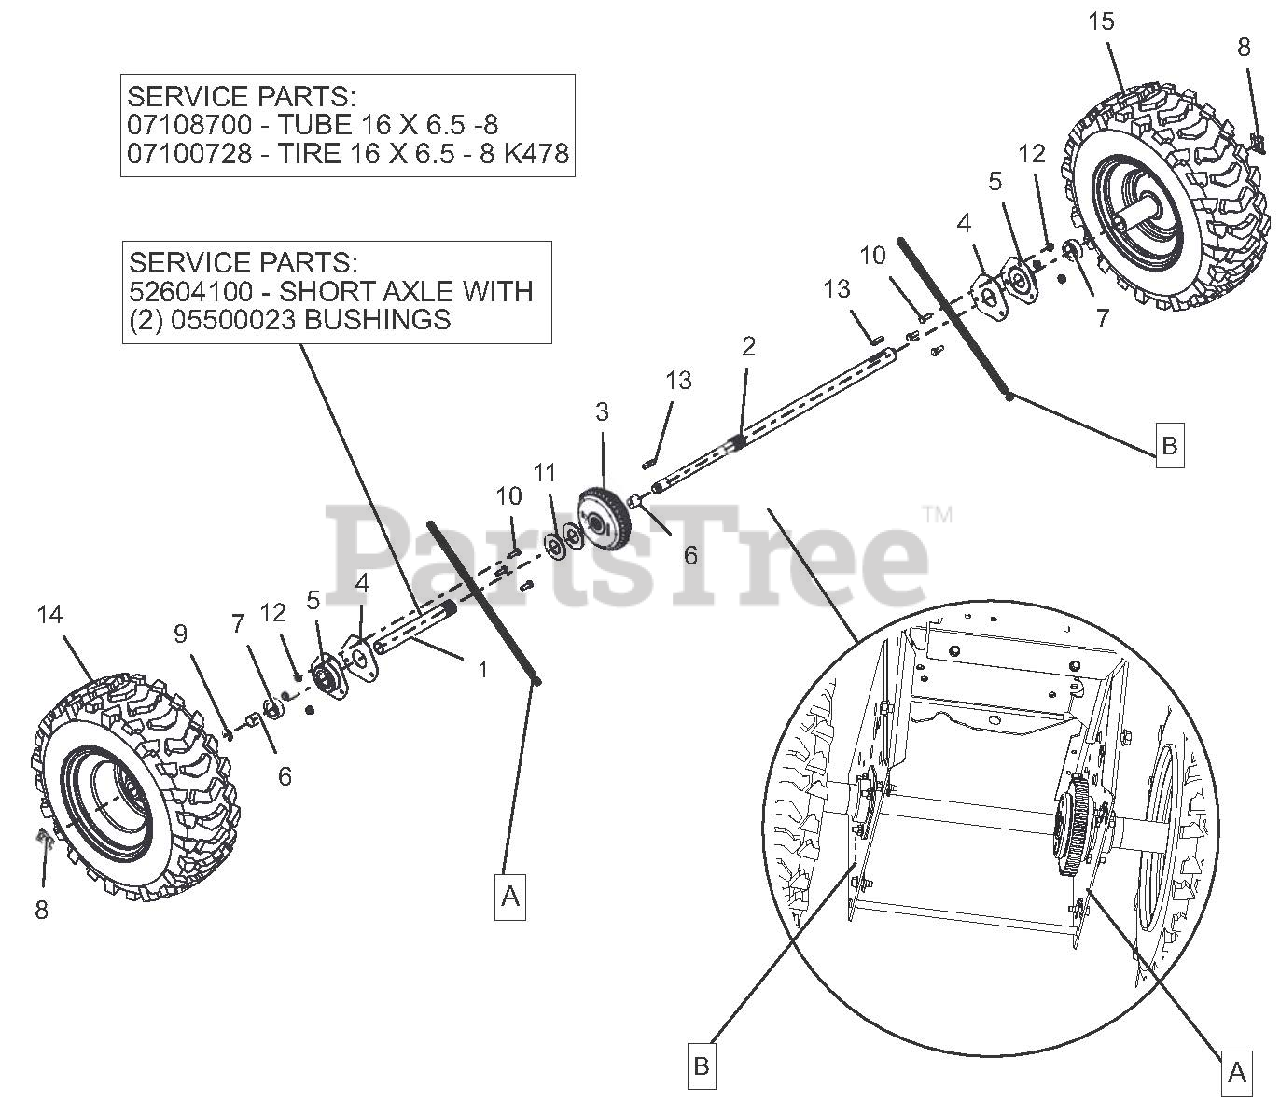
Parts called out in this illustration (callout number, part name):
1	AXLE, SHORT-PRO AUTO DIFF
1	AXLE, SHORT-AUTO W/BUSHINGS
1	BSHG-SLV .706X.764X.75 BRZ
2	AXLE, LONG-PRO AUTO DIFF
3	DIFFERENTIAL, AUTOMATIC
4	PLATE, BEARING SPACER
5	BRG-FLG 1.003/1.000 3 BOLT
6	BSHG-SLV .706X.764X.75 BRZ
7	SPACER, PRO AXLE BEARING
8	CLIP, SNAP .625 DIA
9	RG-RTNG-EXT .625X.042
10	@BLT-HEX .25-20X.75 GR5 YWZC
11	WSHR-FL-STL- 1.062X2.0X.134 YZ
12	@NUT-LK-CTR-FLG .25-20 YWZC
13	KEY-RECT .25X.188X1.00
14	TIRE/WHEEL, RH 16X6.50-8 DIFF
15	TIRE/WHEEL, LH 16X6.50-8 DIFF
16	TUBE
17	TIRE, 16X6.50-8 K478
